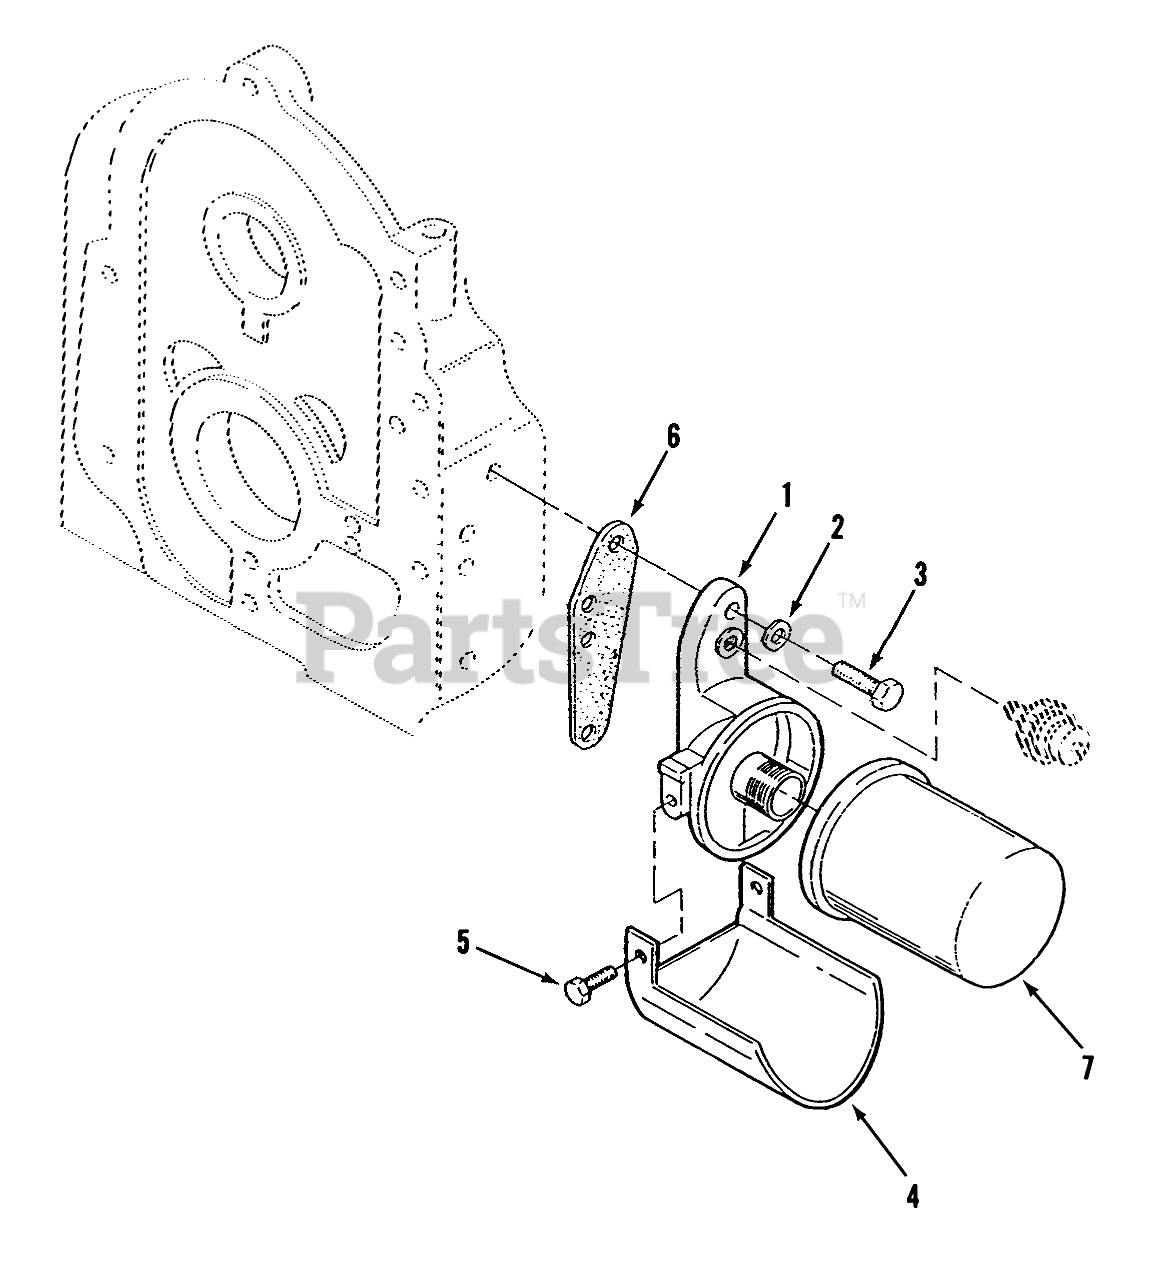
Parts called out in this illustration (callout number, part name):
1	Adapter
2	Washer
3	HHCS 5/16-18 X 1
4	Oil Filter Drain
5	Bolt
6	Gasket
7	Oil Filter
